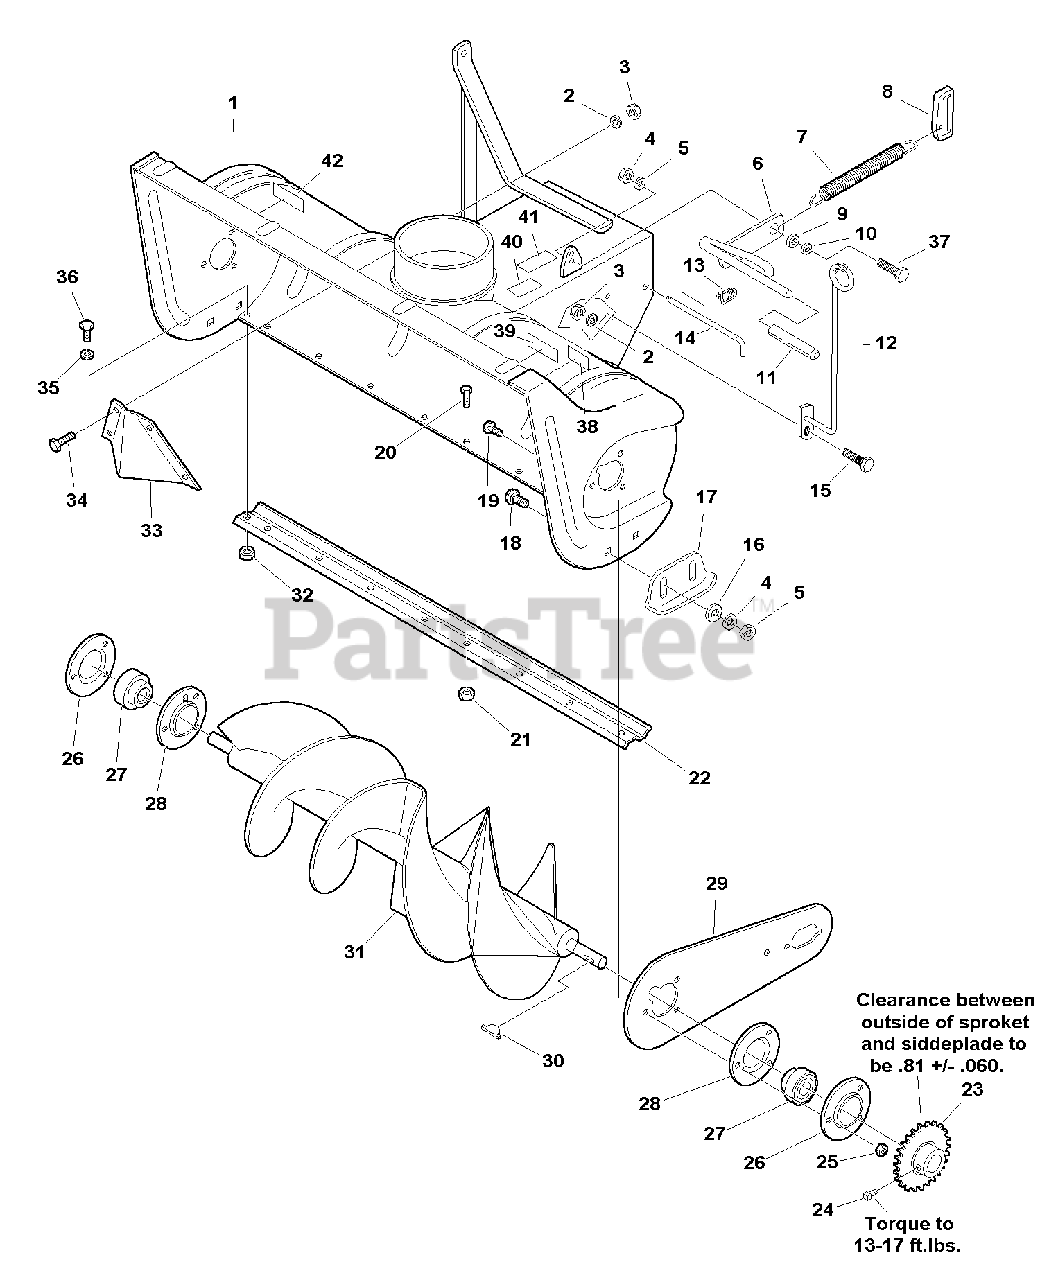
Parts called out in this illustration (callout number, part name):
1	BODY & FRAME ASSEMBLY
2	LOCKWASHER
3	NUT, Hex, 5/16-18
4	LOCKWASHER
5	NUT, Hex, 3/8-16
6	LEVER & ROD ASSEMBLY
7	SPRING, Extension
8	ANCHOR, Spring
10	WASHER
11	GRIP, Black Vinyl
12	GUIDE, Cable
13	PIN, Safety
14	PIN, Clevis
15	CAPSCREW, Hex Head, 5/16-18 x 1
16	WASHER
17	SKID & WEAR ASSEMBLY
18	CARRIAGE BOLT, 3/8-16 x 3/4
19	CAPSCREW, Hex Head, 5/16-18 x 7/8
20	CAPSCREW, Hex Head, 1/4-20 x 5/8
21	NUT, Hex Centerlock, 1/4-20
22	BLADE, Scraper
24	SCREW, Set, Square Head, Cup Point 5/16-18 x 1/2, G8
25	NUT, Hex Flange Lock, 5/16-18
26	FLANGE, Bearing
27	BEARING, Cartridge
28	FLANGE, Bearing
29	PLATE, Side
31	ROTOR ASSEMBLY
32	NUT, Hex Centerlock, 5/16-18
34	CAPSCREW, Hex Head, 5/16-18 x 5/8
36	CAPSCREW, Hex Head, 5/16-18 x 3/4
37	CAPSCREW, Hex Head, 3/8-16 x 1-1/4
38	DECAL, Danger Auger
39	DECAL, Caution
40	DECAL, Model Number & Serial Number, Not Serviced
41	DECAL, OPEI, Not Serviced
42	DECAL, Caution
